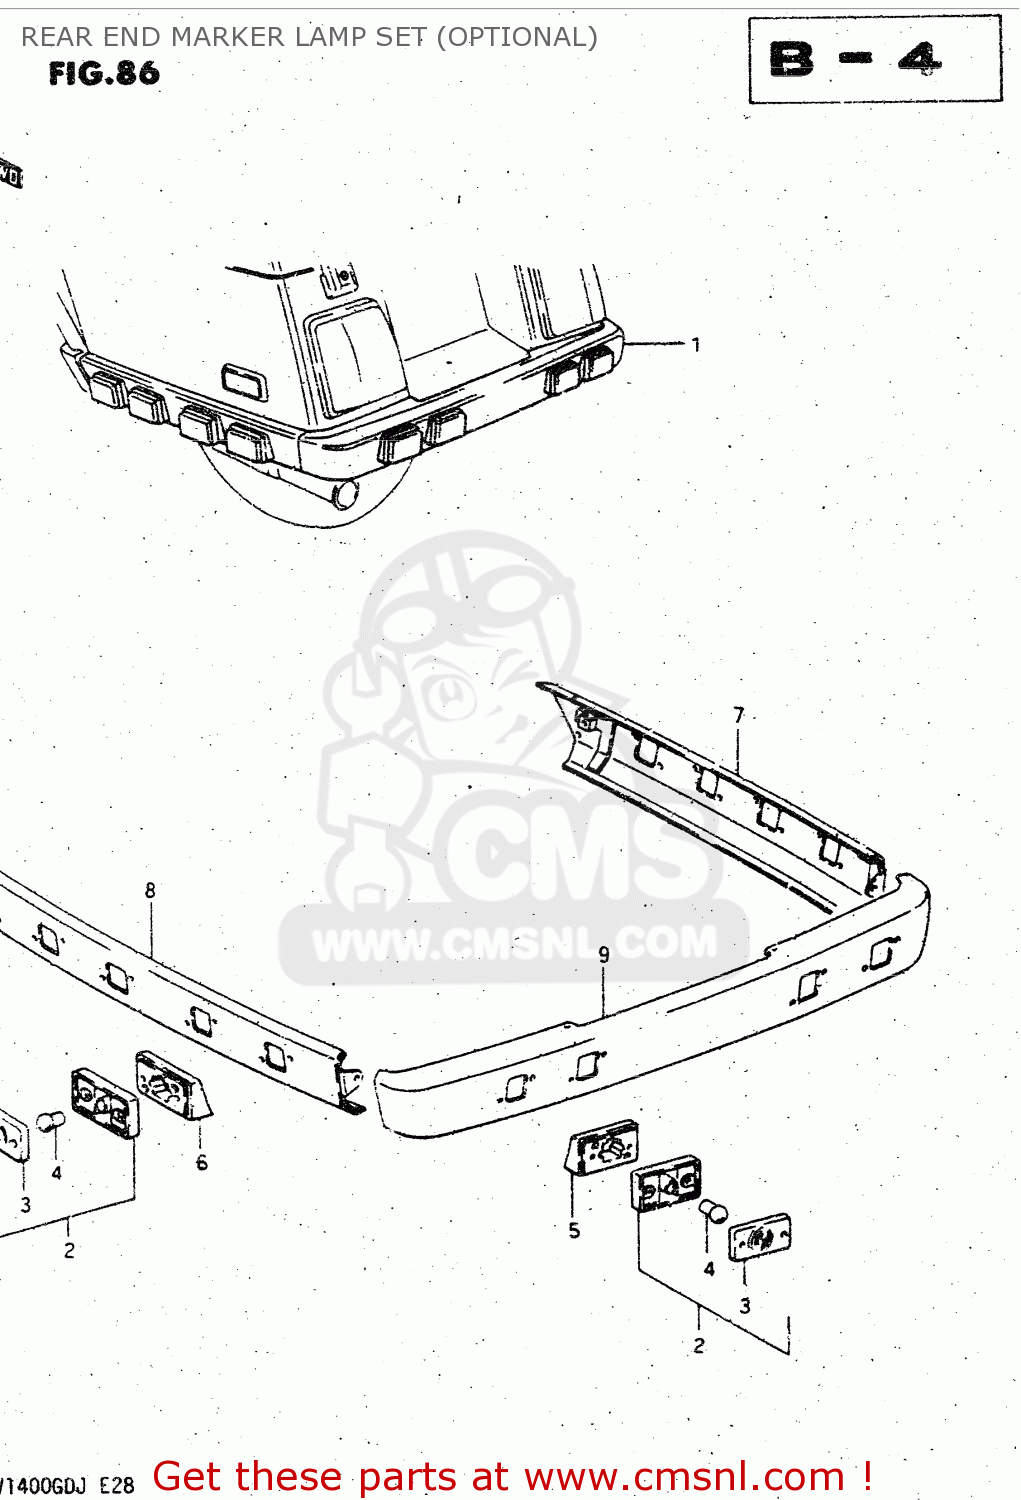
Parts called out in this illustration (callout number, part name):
1	REAR END,MARKER LAMP S
2	TRAVEL TRUNK,MARKER LAMP
3	LENS
4	BULB 12V 3W
5	BASE,MARKER LAMP MOUNT
6	BASE,MARKER LAMP MOUNT
7	REAR END,RIGHT COVER
8	REAR END,LEFT COVER
9	TRIM,SIDE BAG CARRIER
